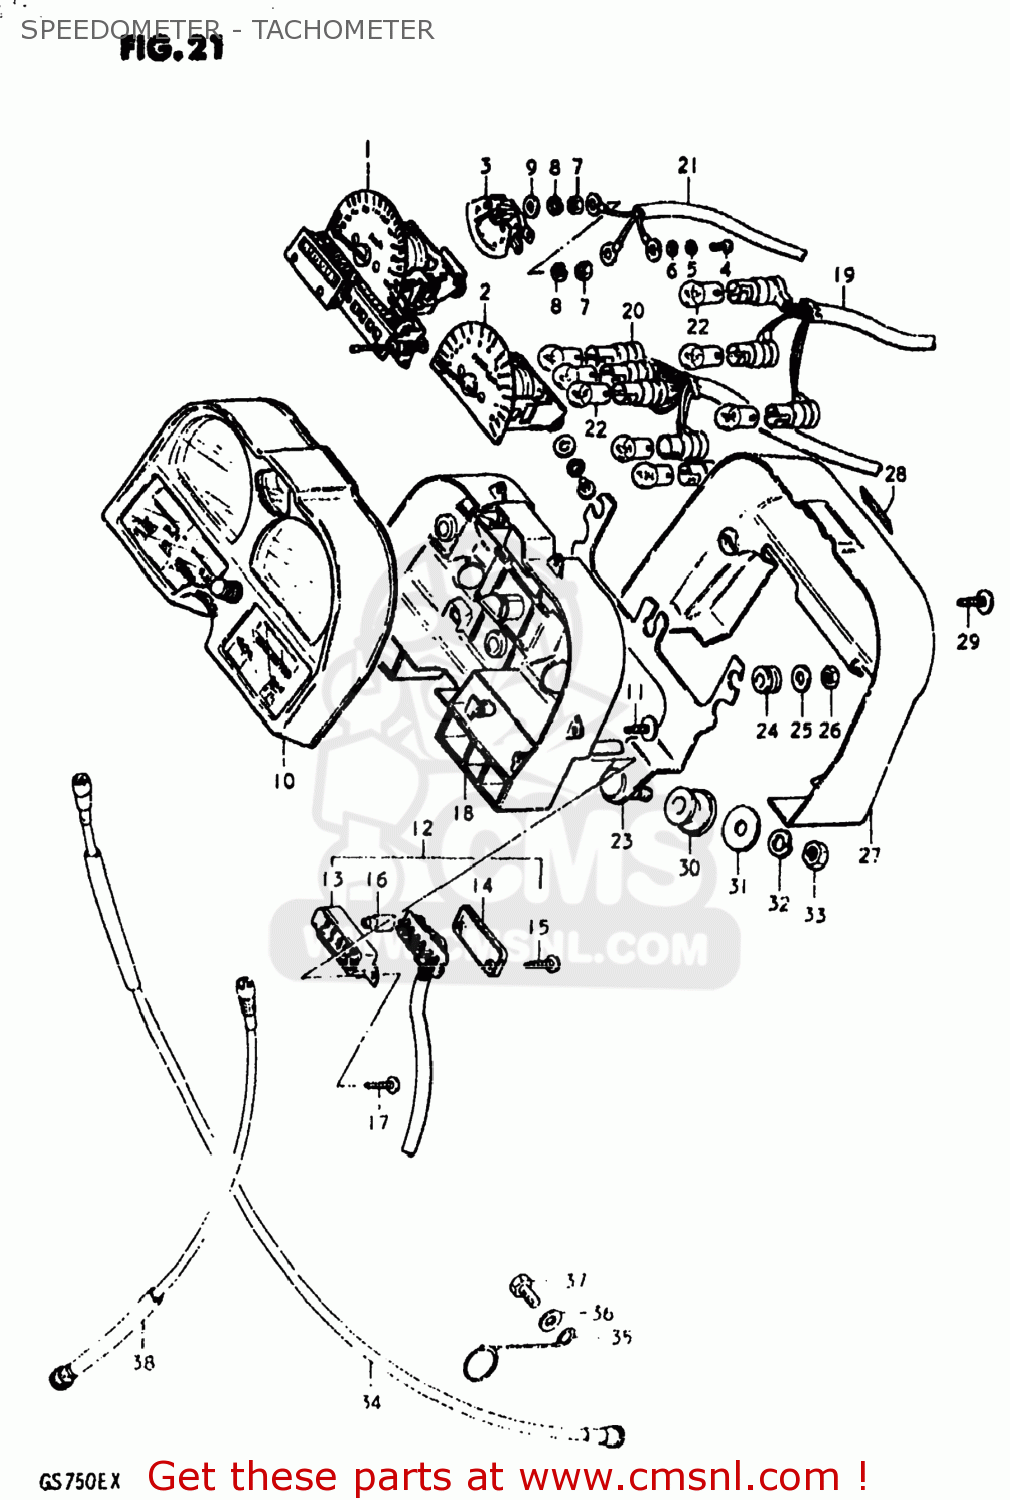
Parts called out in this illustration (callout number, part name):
1	SPEEDOMETER
2	TACHOMETER
3	METER,FUEL
4	SCREW 3X12
5	LOCK WASHER
6	WASHER
7	NUT 4MM
8	LOCK WASHER
9	WASHER
10	HOOD,METER
11	SCREW
12	INDICATOR ASSEMBLY,GEAR POSITION
13	CASE,GEAR INDICATOR
14	COVER,LWR
15	SCREW,GEAR INDICATOR
16	BULB(14V1.12W)
17	SCREW
18	CASE,COMBINATION METER
19	SOCKET,METER
20	SOCKET
21	LEAD WIRE,FUEL METER
22	BULB(12V3.4W,T10)
23	BRACKET,METER
24	CUSHION,METER
25	WASHER,METER
26	NUT
27	COVER,METER,UNDER
28	EMBLEM
29	SCREW
30	CUSHION,METER
31	WASHER (8.5X29X1.6)
32	LOCK WASHER
33	NUT
34	CABLE ASSEMBLY,SPEEDOMETER
35	GUIDE,SPEEDOMETER CABLE
36	WASHER
37	BOLT, UPPER
38	CABLE ASSEMBLY,TACHOMETER
